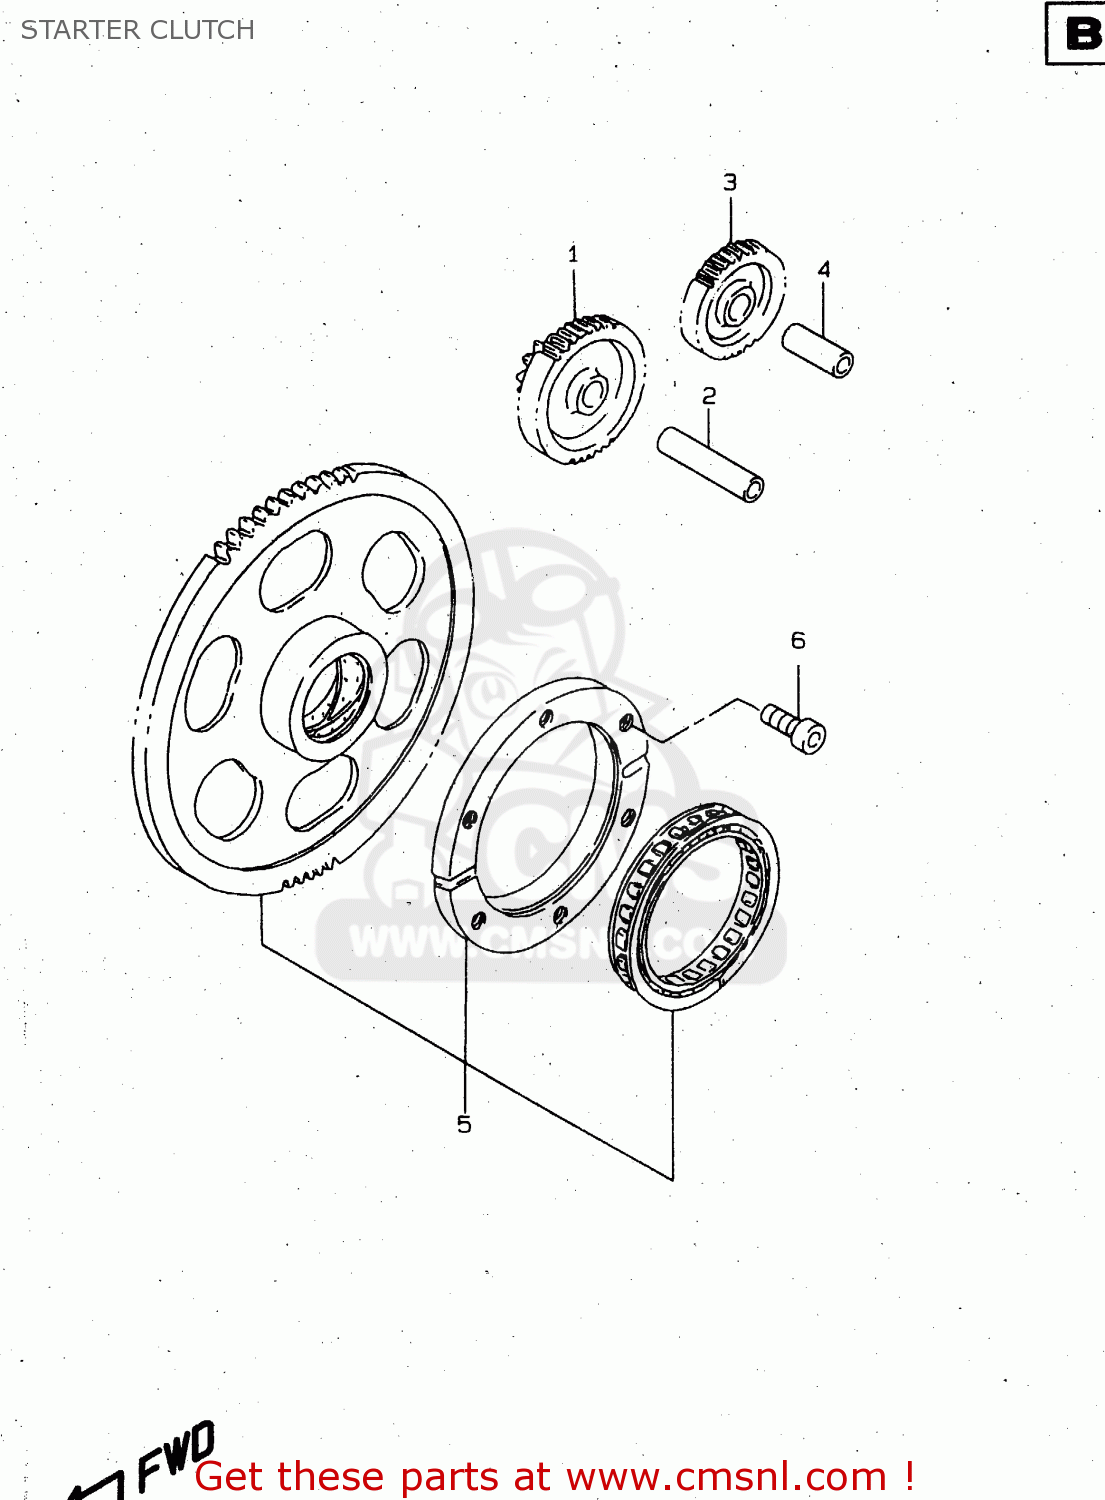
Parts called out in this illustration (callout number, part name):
1	GEAR,STARTER IDLE NO.1
2	PIN,10X43
3	GEAR,STARTER IDLE NO.2
4	PIN
5	CLUTCH SET,STARTER
6	BOLT
